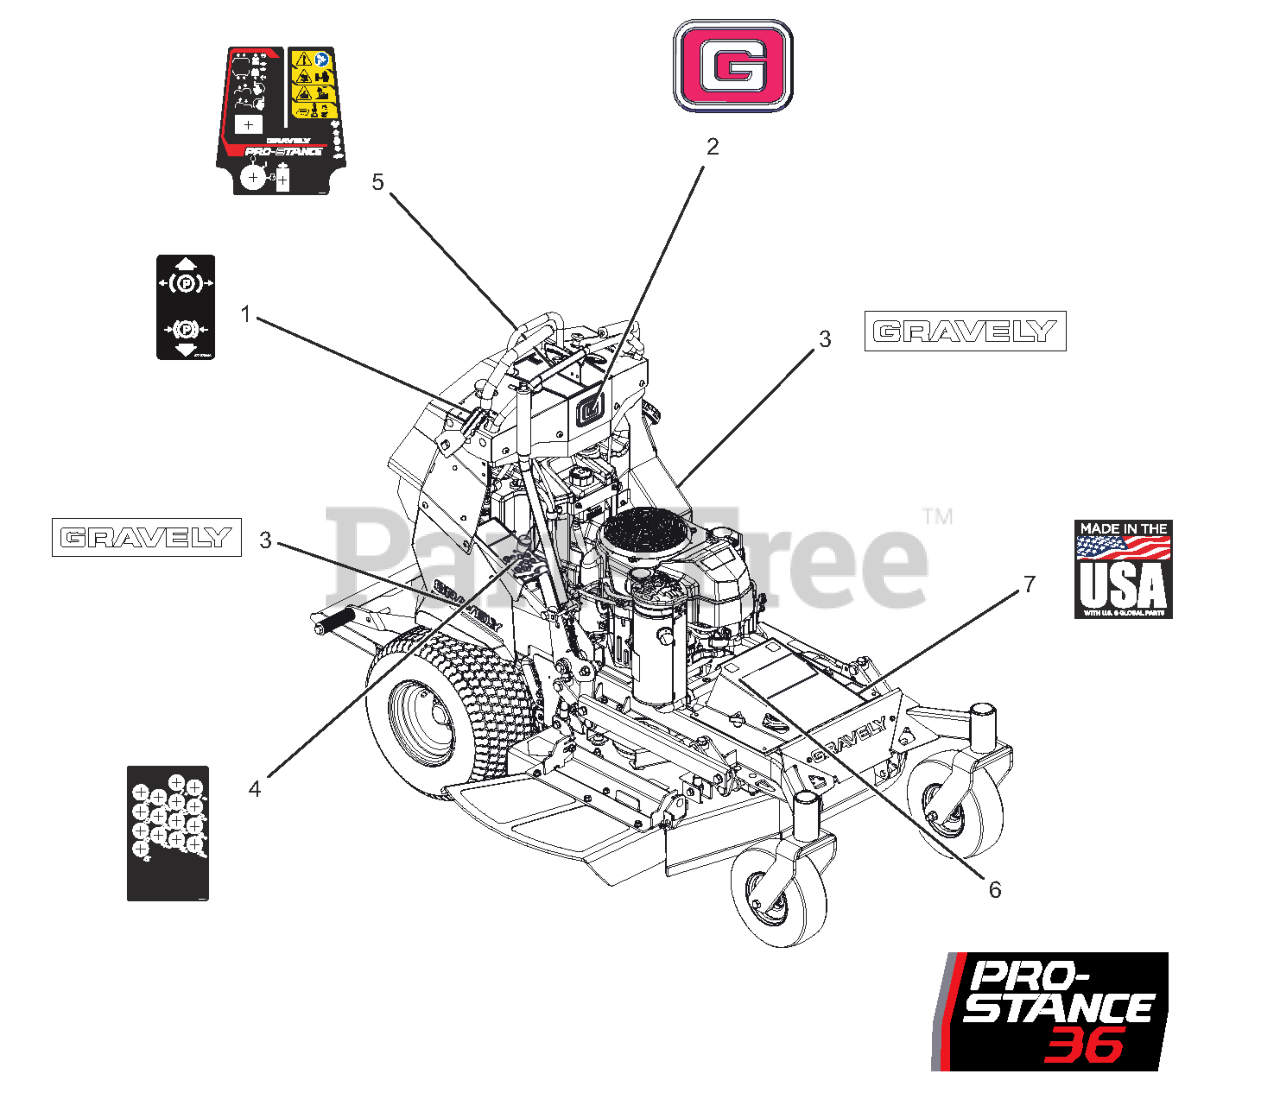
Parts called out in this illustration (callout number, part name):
1	DECAL, PARKING BRAKE LEVER
2	DECAL, GRAVELY BRAND
3	DECAL, 9.5" GRAVELY LOGO
5	DECAL, DASH - PROSTANCE
7	DECAL, MADE IN USA
